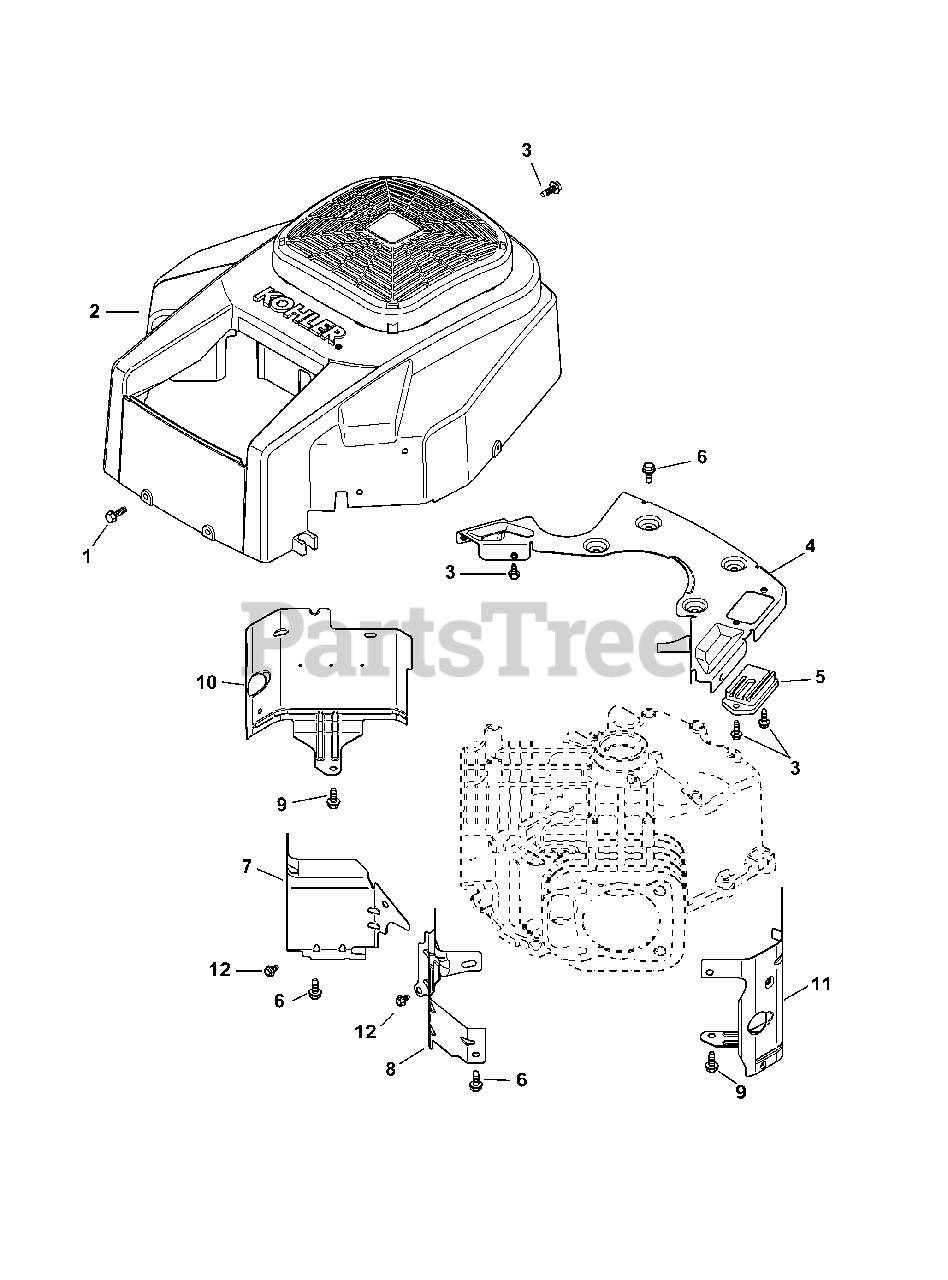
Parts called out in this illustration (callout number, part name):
1	Screw, M6 x 1.7 x 18
2	Blower Housing Kit
3	Flange Screw, M5 x .8 x 16
4	Backing Plate Kit
5	Regulator/Rectifier
6	Flange Screw, M6 x 1.0 x 16
7	Valley Baffle, #1 Cylinder
8	Valley Baffle, #2 Cylinder
9	Flange Screw, M6 x 1.0 x 10
10	Cylinder Barrel Baffle, #1 Side
11	Cylinder Barrel Baffle, #2 Side
12	Flange Screw, M5 x .8 x 10
